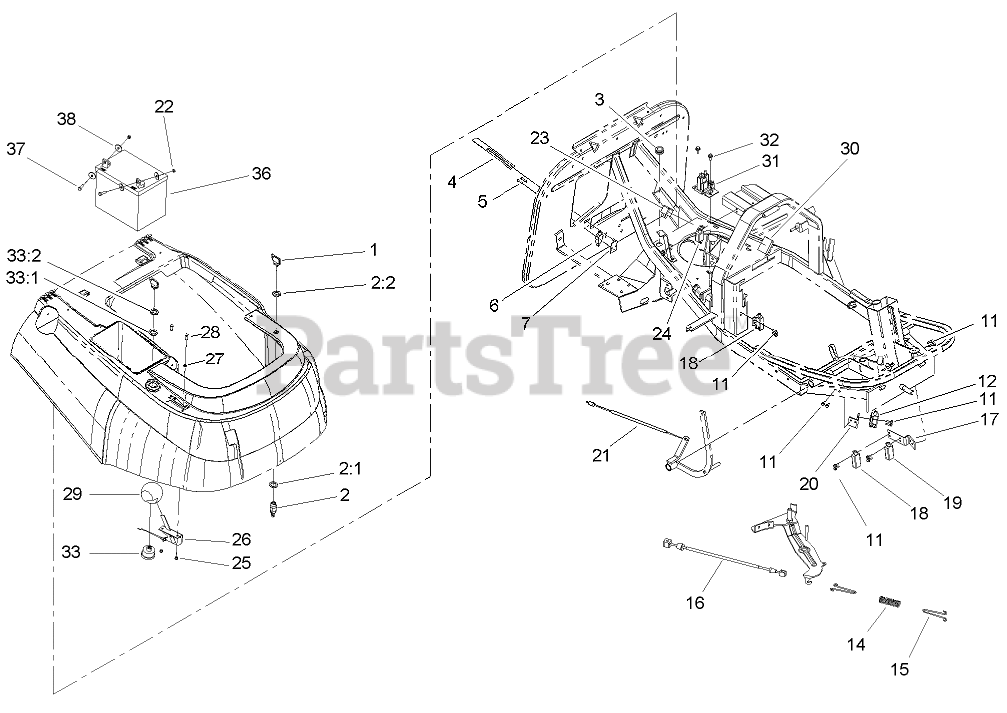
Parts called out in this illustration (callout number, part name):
1	KEY-IGNITION
2	STARTER SWITCH ASM
2:1	WASHER-TOOTH, INTERNAL
2:2	NUT-HH
3	Grommet
4	Lever-Bag Fill
6	Switch
7	Clamp-Bag Fill
11	SCREW-HH, TAP
12	SWITCH-DOUBLE, POLE
14	Spring-Compression
15	Hook-Spring
17	Bracket-Switch
18	SWITCH-INTERLOCK
19	SWITCH-POLE, SINGLE
20	Bracket-Switch
21	CABLE-BRAKE
22	NUT-HEX
23	RELAY
24	SWITCH-POLE, SINGLE
25	NUT-LOCK
26	Throttle Cable ASM
27	WASHER
28	SCREW-HH
30	MODULE
31	SOLENOID
32	SCREW-HHF, TAP
33	Key Switch ASM
33:1	WASHER-TOOTH, INTERNAL
33:2	NUT-HH
36	BATTERY-155 CCA
37	SCREW-HH
38	Washer-Flat
